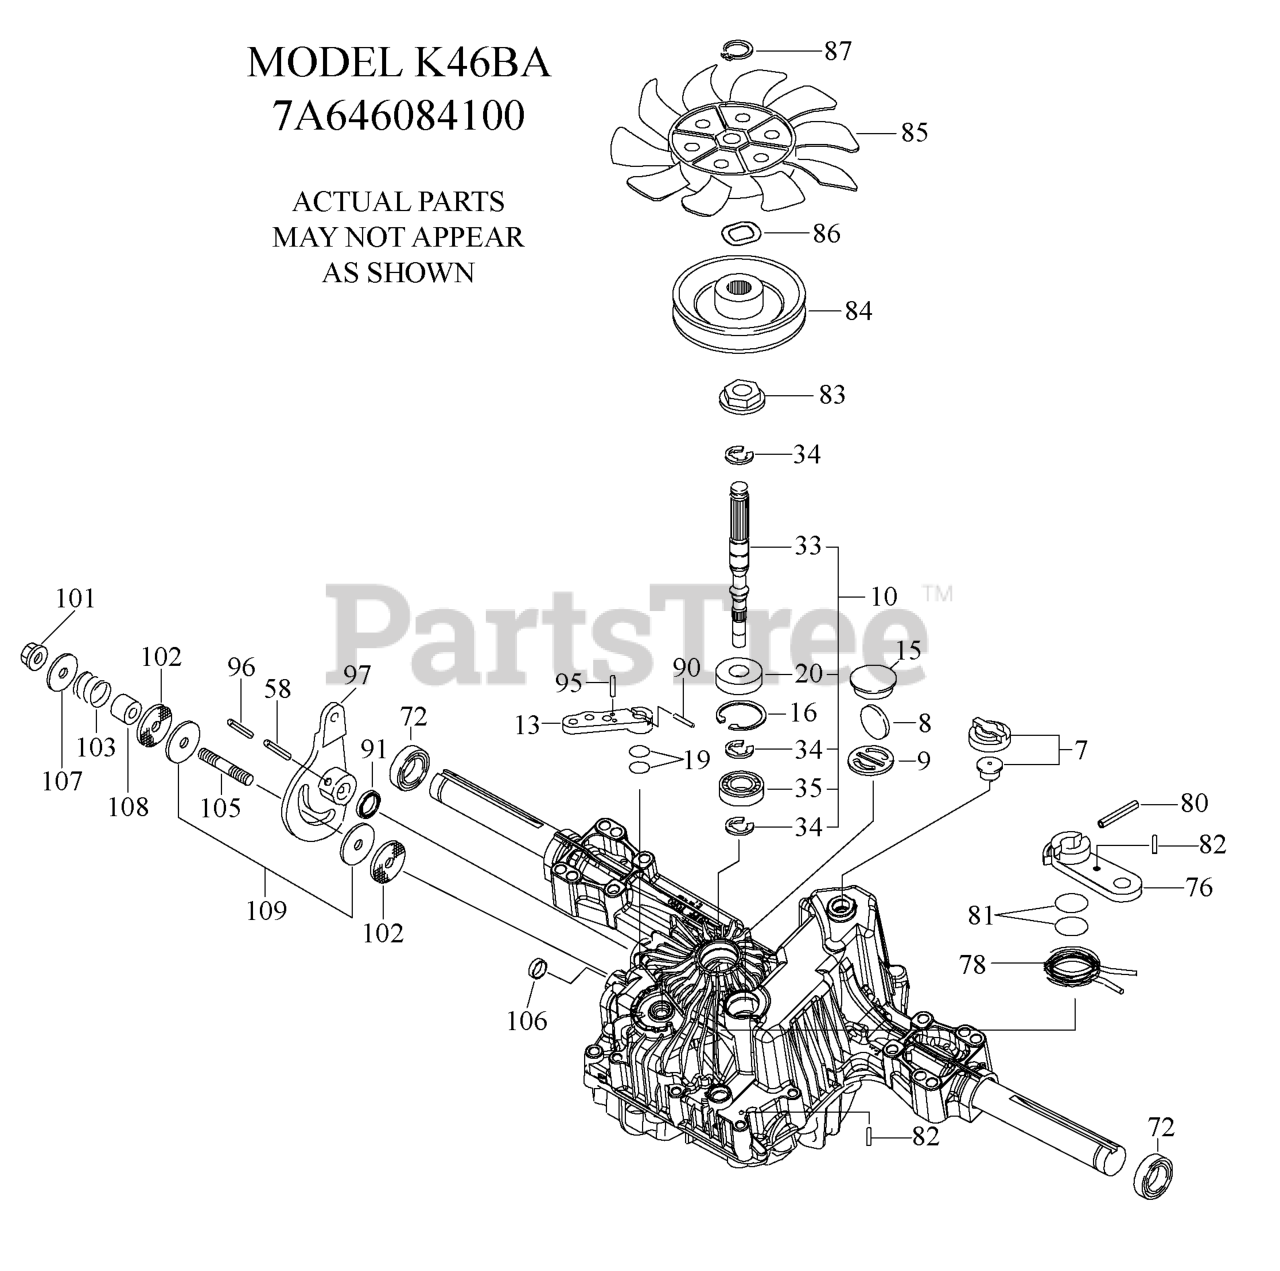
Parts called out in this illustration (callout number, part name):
7	VENT
8	MAGNET
9	Magnet Holder
10	Pump Shaft/Bearing Kit
13	LEVER
15	Sealing Cap 30
16	Snap Ring C 35
19	O-RING
20	SEAL
33	Pump Shaft (Standard
35	Bearing 6202c3
58	PIN.ROLL.640.22351060040
72	SEAL.19, 19216334280
76	Brake Lever
78	SPRING
80	SPRING
81	O-RING
82	PEN
83	SPINE COLLAR
84	PULLEY
85	Fan, Black
86	WASHER
87	RING
90	PEN
91	SEAL
95	PIN.SPR.3.0A
96	PEN
97	Control Lever
101	Lock Nut 10
102	Washer 10 x 40 x 4
105	Stud 10 x 60
106	Sealing Cap 18
107	Washer 10 x 36 x 2.8
108	Collar 10 x 20 x 17
109	Friction Plate Kit
